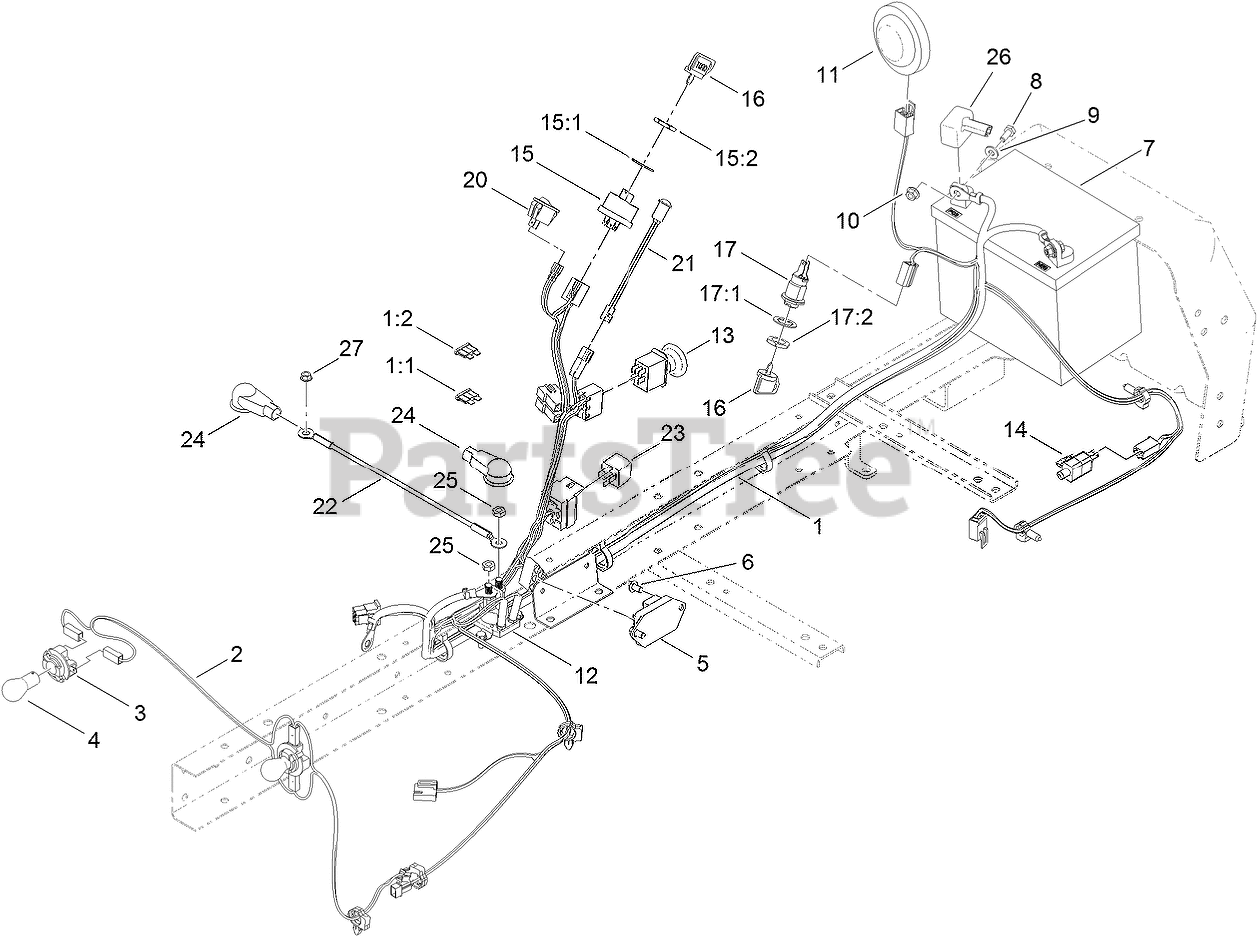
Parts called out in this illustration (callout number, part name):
1	HARNESS-WIRE
1:1	FUSE-BLADE, 30 AMP
1:2	FUSE-BLADE, 25 AMP
2	HARNESS-HEADLIGHT
3	SOCKET-HEADLIGHT
4	BULB
5	MODULE-CLUTCH
6	SCREW-HWH
7	BATTERY
8	SCREW-HH
9	WASHER-FLAT
10	NUT-HF
11	SWITCH-SEAT
12	SOLENOID
13	SWITCH-PTO
14	SWITCH
15	Key Switch ASM
15:1	WASHER-TOOTH, INTERNAL
15:2	NUT-HH
16	KEY-IGNITION
17	STARTER SWITCH ASM
17:1	WASHER-TOOTH, INTERNAL
17:2	NUT-HH
20	SWITCH-ROCKER
21	LIGHT-INDICATOR
22	WIRE-SOLENOID/STARTER
23	RELAY
24	BOOT-INSULATOR, TERMINAL
25	NUT-JAM
26	BOOT-TERMINAL
27	NUT-HF
